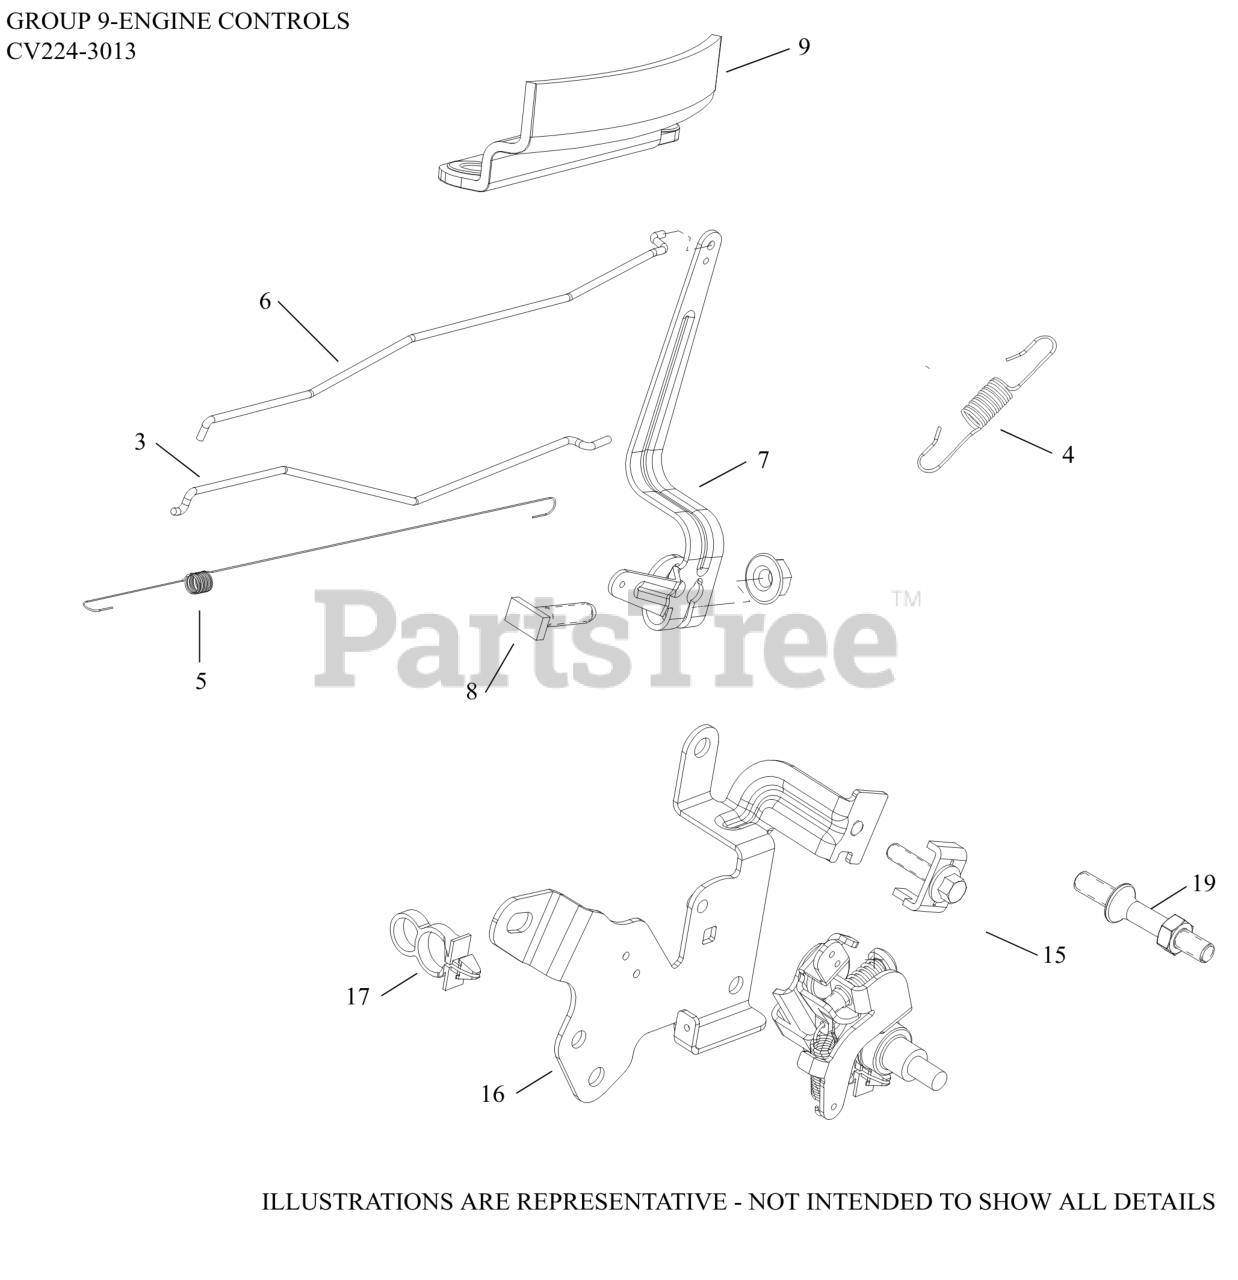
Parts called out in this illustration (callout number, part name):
3	LINKAGE, CHOKE
4	SPRING, GOVERNOR
5	SPRING, LINKAGE
6	LINKAGE, GOVERNOR
7	LEVER, GOVERNOR
8	SCREW, RECTANGLE HEAD (M6)
9	GUARD, FINGER
15	CONTROL ASSEMBLY, VARIABLE SPEED
17	CLIP, FUEL LINE
